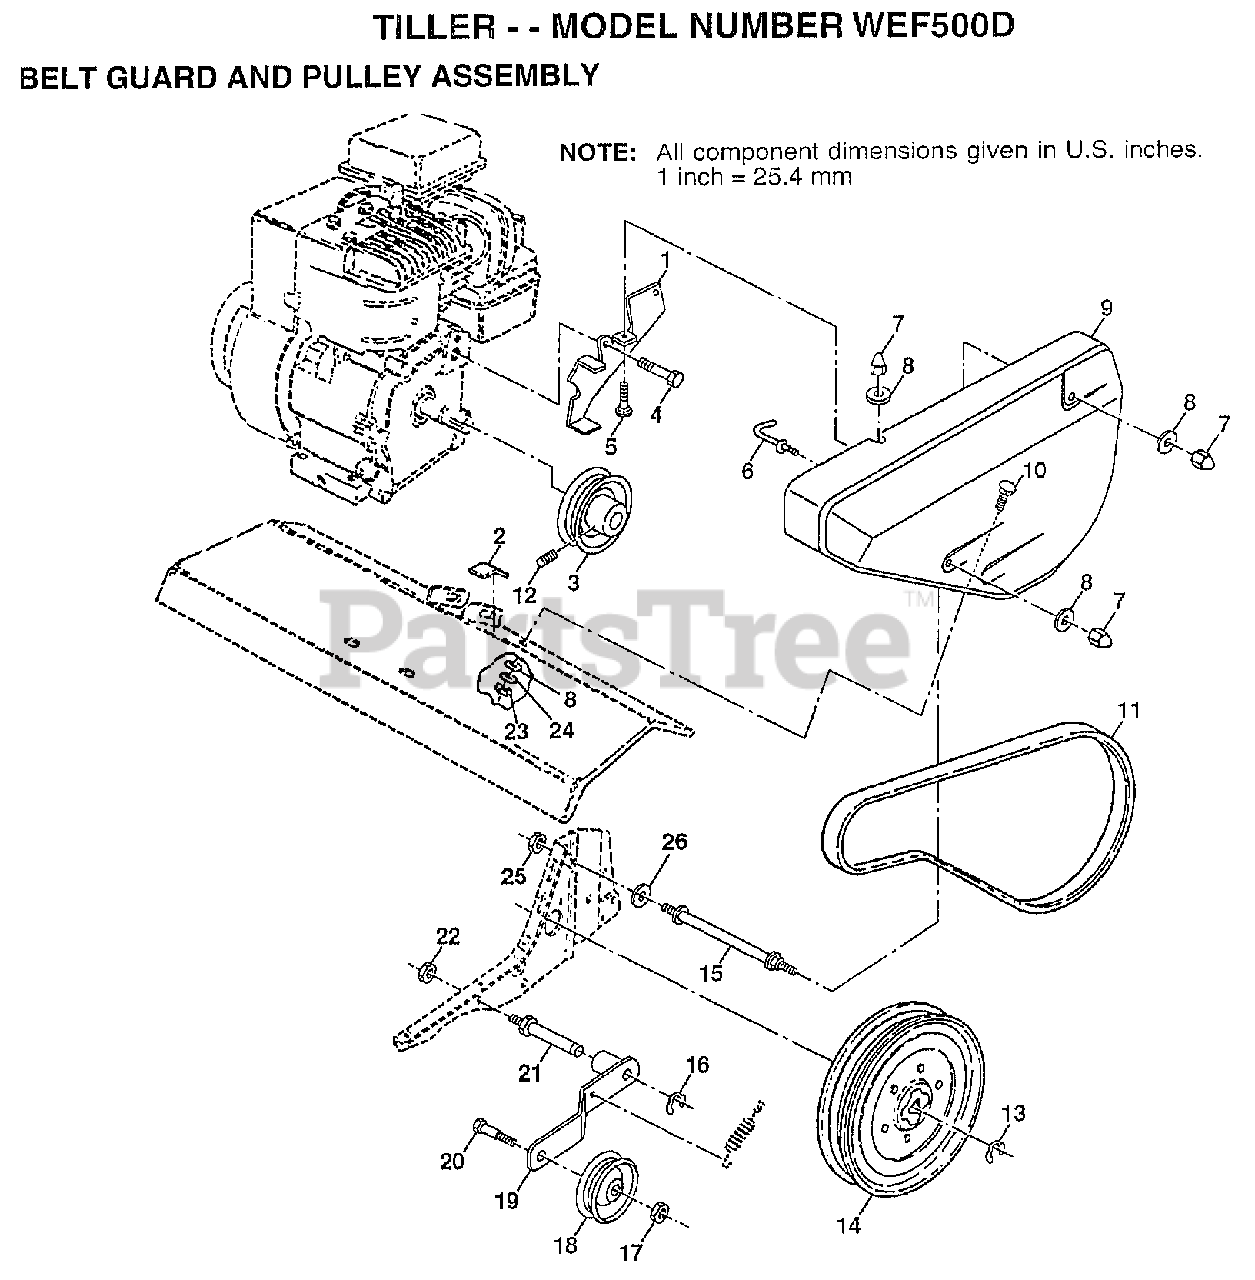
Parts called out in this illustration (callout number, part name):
1	SET SCREW
4	BOLT
7	NUT-CAP TI
8	WASHER
9	GUARD.BELT.TILLER
10	PAD IDLER TI
11	BOLT T
14	PULLEY.TRANSMISSN
16	KLIP RING TI
17	NUT
19	IDLER ARM TI
21	SHAFT IDLER TI
22	SHIELD-DIRT TI
23	LOCKWASHER
25	JAM NUT TI
